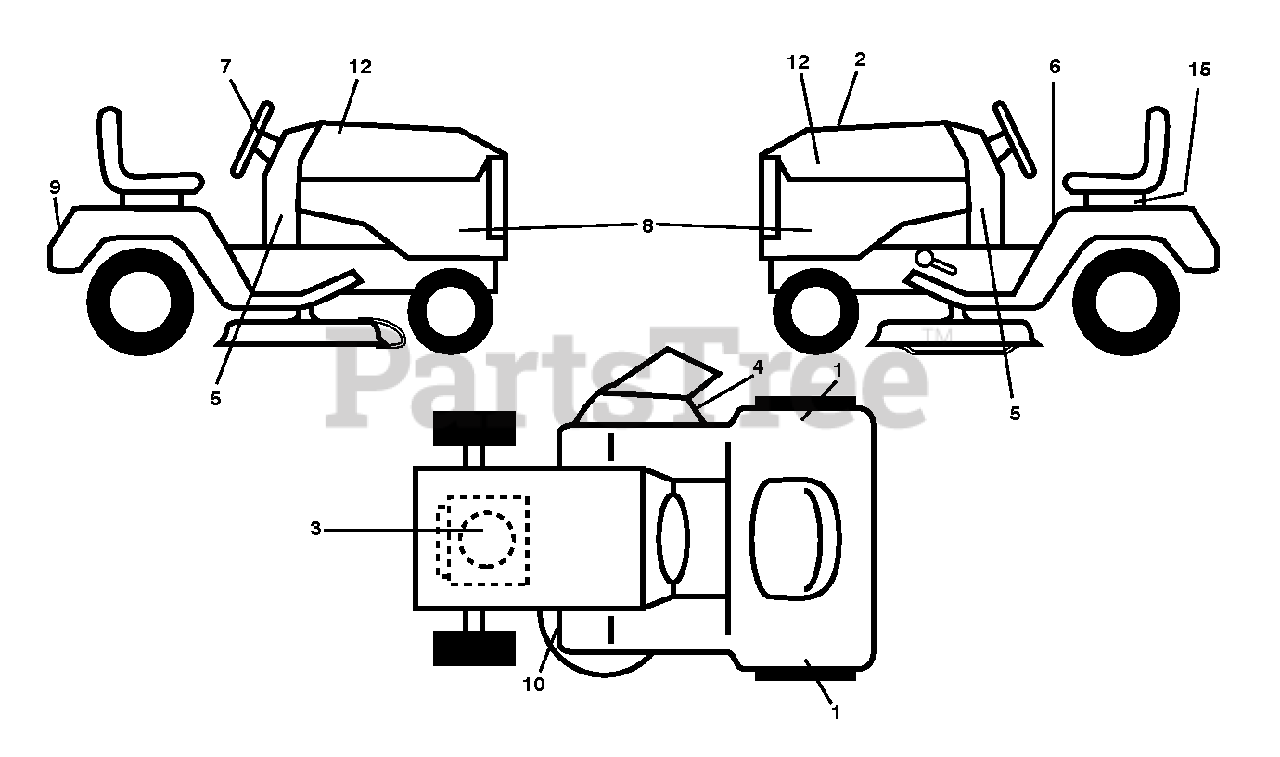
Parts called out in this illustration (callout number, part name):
3	DECAL.ENG.BS.5HP.PB.278978
4	DECAL.WARN.KEEP.HAND.AWAY
6	Fender Engine Warning Decal
7	DECAL.STEER.WHEEL.POULAN.PRO
9	DECAL.REAR.FNDR.LOGO.POULAN.PR
10	DECAL V BELT SCHEMATIC
12	DECAL.HOOD.POULAN.PRO.SET
15	DECAL BTRY SYMBOLS
